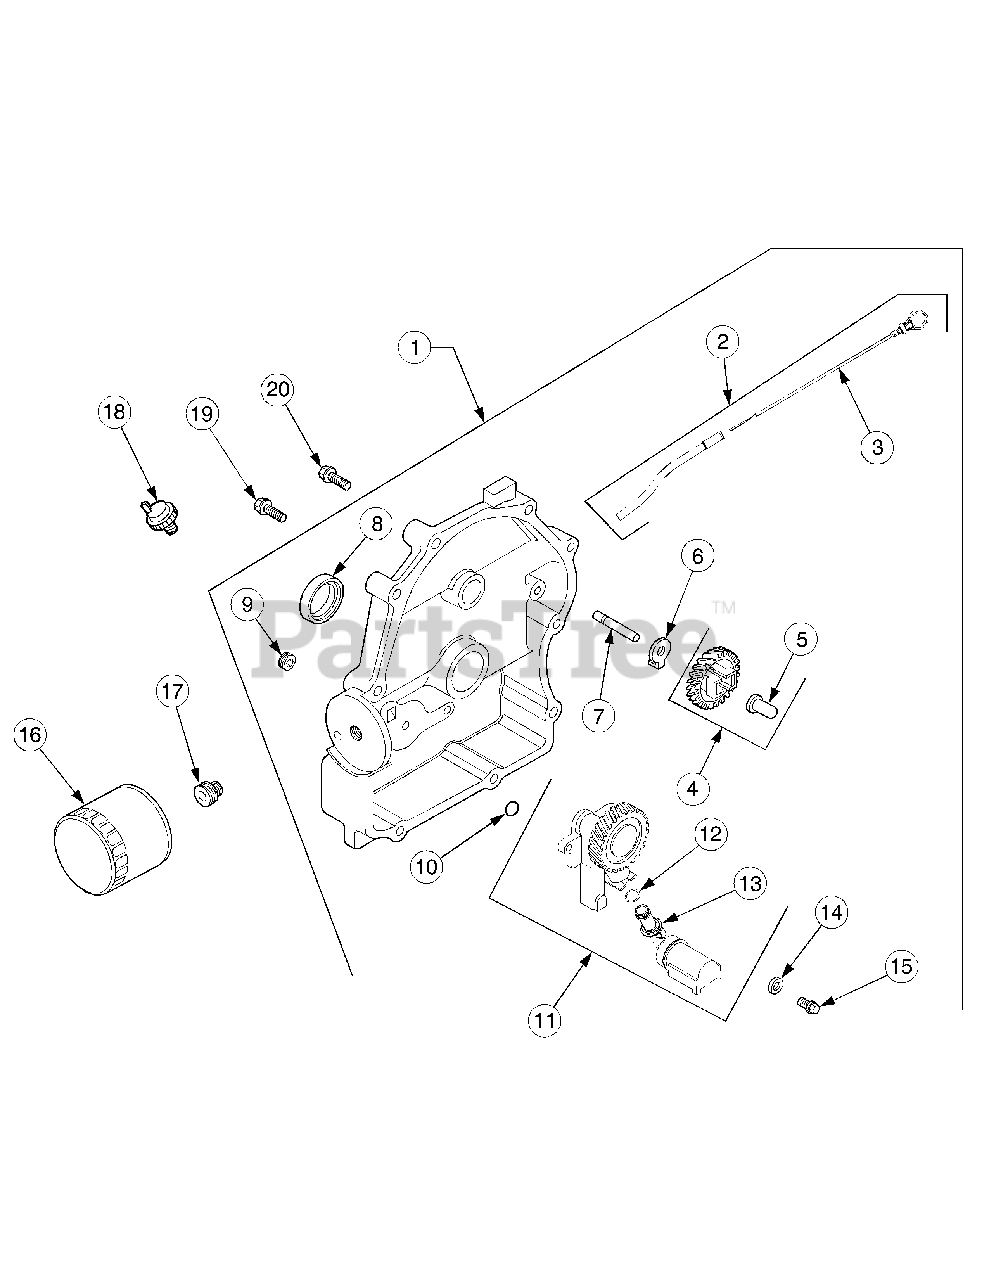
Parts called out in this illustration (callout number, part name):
1	Plate Assy, Closure (Incl. Ref #2-15)
2	Kit, Tube w/Dipstick
4	Kit, Governor Gear (Incl. Ref #6)
5	Pin, Governor Regulating
7	Shaft, Governor Gear
8	Seal, Oil (PTO end)
9	Plug, Pipe 1/8
11	Oil Pump Assy (Incl. Ref #13-14)
12	O-Ring, Oil Pick-up
13	Pick-up, Oil
14	Washer, Plain
15	Screw, Hex Flange, M6 x 1.0 x 25
16	Filter, Oil
17	Nipple, Oil Filter
18	Switch, Pressure
19	Screw, Hex Flange, M8 x 1.25 x 45
20	Screw, Hex Flange, M8 x 1.25 x 45
